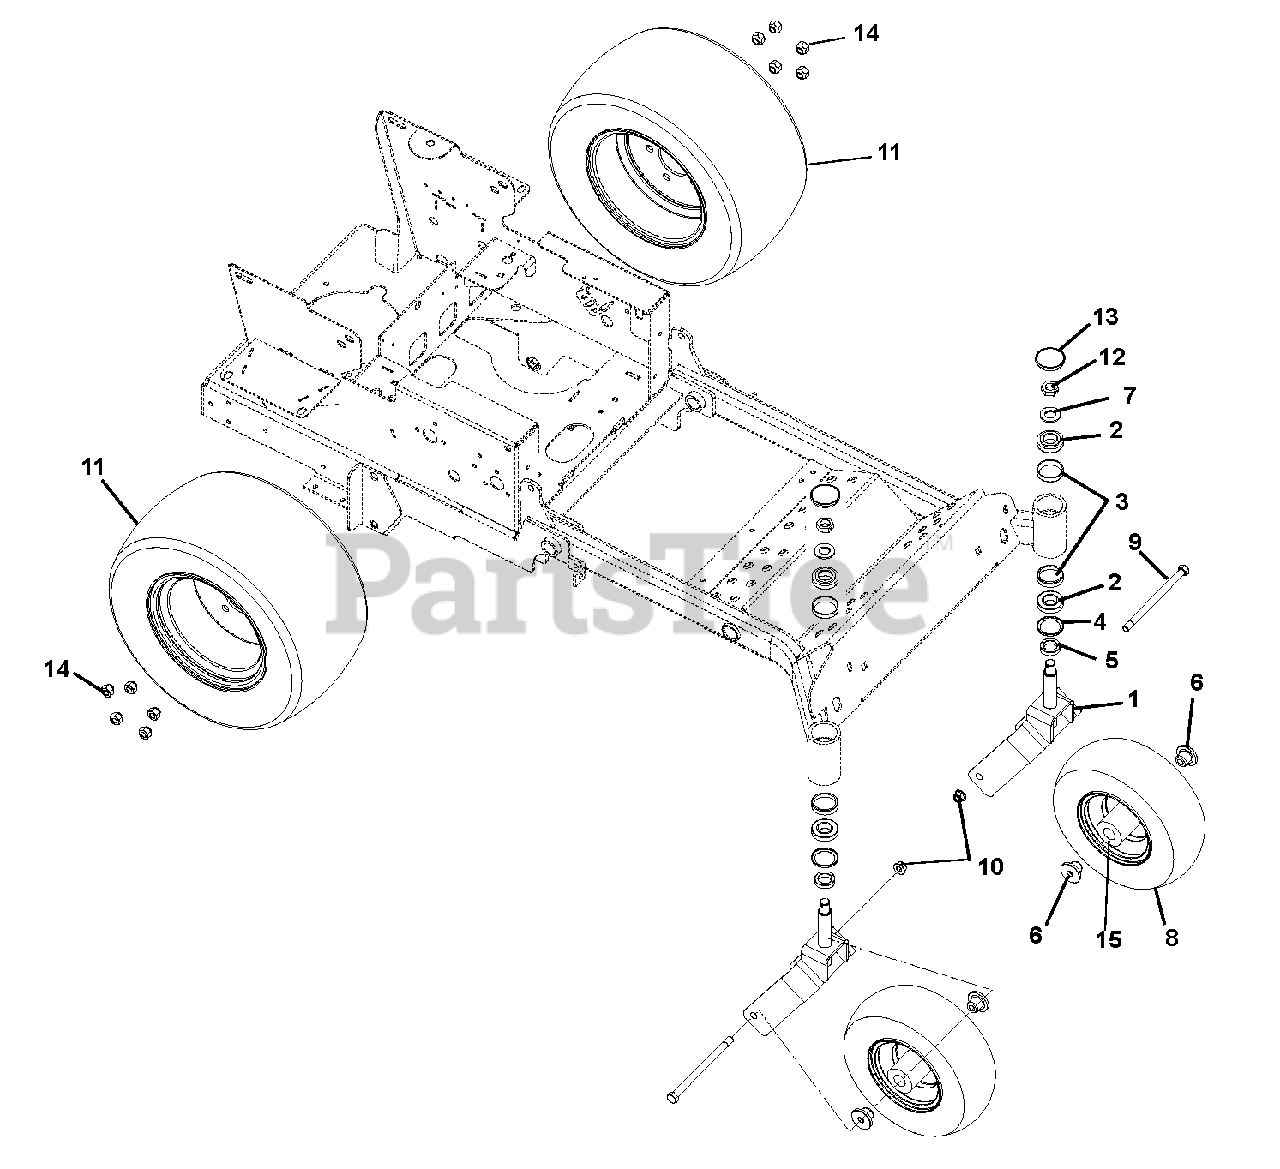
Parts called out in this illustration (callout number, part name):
1	Weldment, Front Fork (035 - SN 000300 and up, 036 - SN 000200 and up)
1	Fork, CZ44" Service Castor (035 - SN 000200 - 000299)
2	Bearing, Cone with Grease, 1.0 x .58
3	Bearing, Cup 1.980 x .420
4	Bearing Seal 1.5 x 2 x .18
5	Spacer, PM, 1.03 I.D. x 1.5 O.D. x .375
6	Spacer, Wheel
7	Washer, Flat-Steel .812 x 1.50 x .135
8	Front Tire/Wheel Assembly, 13 x 5.00-6
8	Tire
9	Bolt, Hex .50-13 x 7.50 Grade 5
10	Nut, Nyloc Flange .50-13
11	Rear Tire/Wheel Assembly, 20 x 10.00-10
12	Nut, Center Lock Jam .75-16
13	Cap, Dust
14	Wheel Nut .50-20
15	Bearing, 25MM ID x 52MM OD x 15MM
